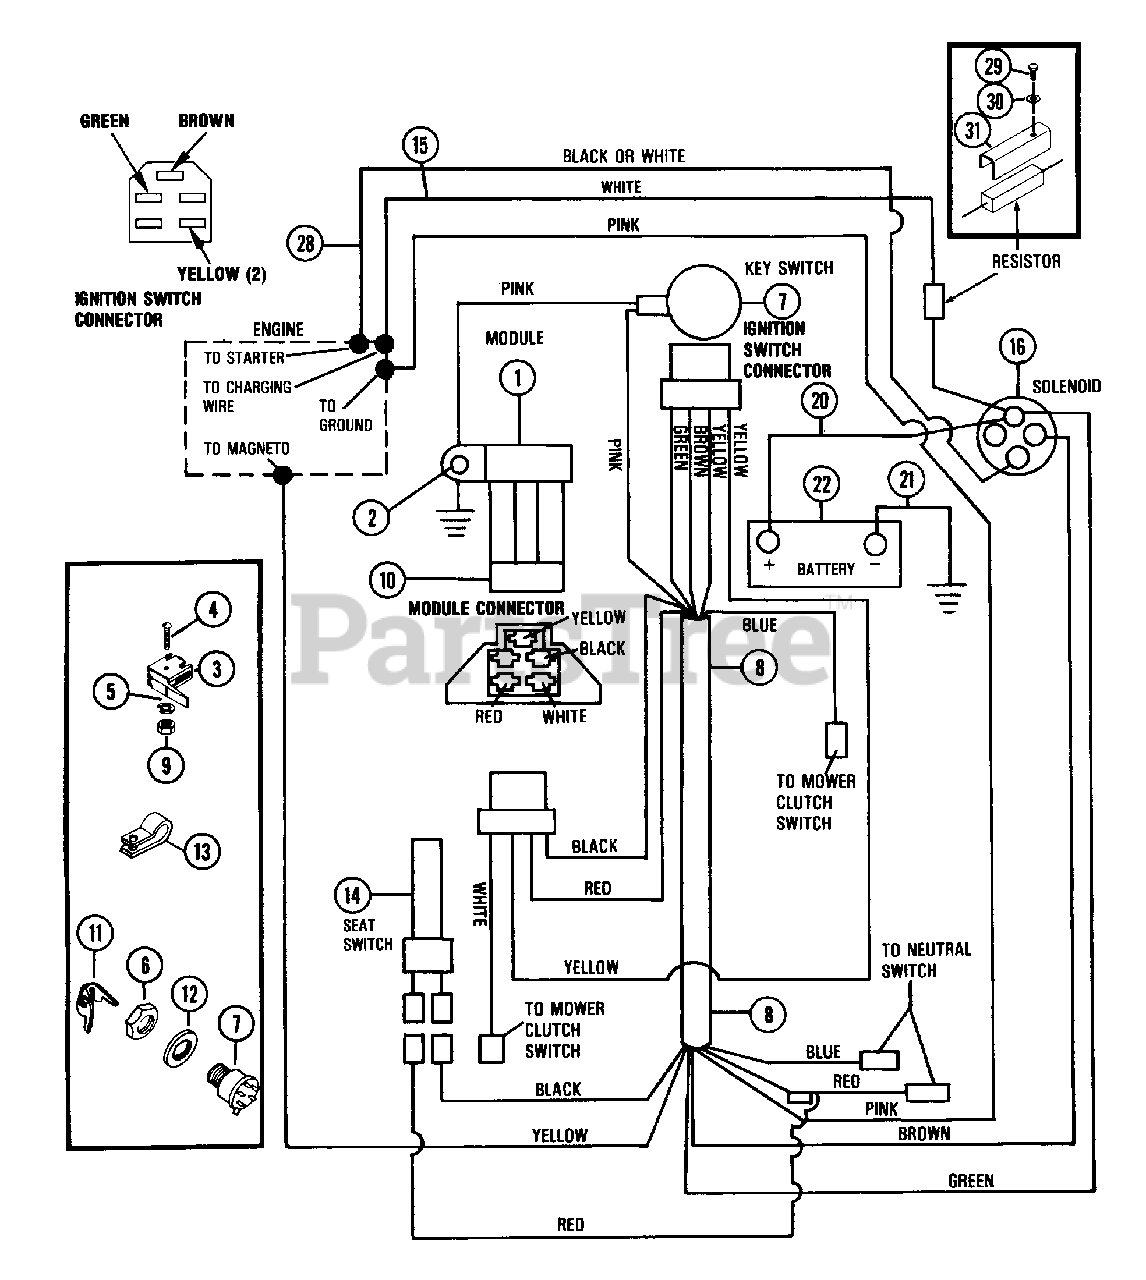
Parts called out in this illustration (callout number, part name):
1	MODULE
2	SCR-TAP 10-12X.50 CRPH PL A
3	SWITCH INTERLOCK
4	SCR-MCH 10-24X1.00 SLRH PL
5	WSHR-LK 10X.047 MED PL
6	NUT .625-32 ALUM
7	IGNITION SWITCH ASSEMBLY
8	WIRE HARNESS
9	NUT-HEX 10-24 PL
10	CONNECTOR
11	KEYS
12	WSHR-LK-INT .625X.045 PL
14	SWITCH SEAT
15	CHARGING WIRE
16	SOLENOID
20	GROUND CABLE .25X13.00X.31
21	GROUND CABLE .25X13.00X.31
22	BATTERY
23	BATTERY TRAY
24	RUBBER PAD
25	BATTERY STRAP
26	HOOK
27	SCR-TAP .312-18X.50 HWH PL TR
28	GROUND CABLE
29	SCR-TAP 10-16X1.0 SLHP PL AB
30	WSHR-FL-STL .250X.562X.049 PL
32	WSHR-LK .312X.097 PL HVY
33	NUT-JAM .312-24 PL
34	WSHR-LK 10X.047 MED PL
35	NUT 10-32 PL
36	NUT-HEX .250-20 PL
37	WSHR-LK-INT .313X.030 PL
38	BLT-RDHDSQNK .25-20X.75 GR5PL
